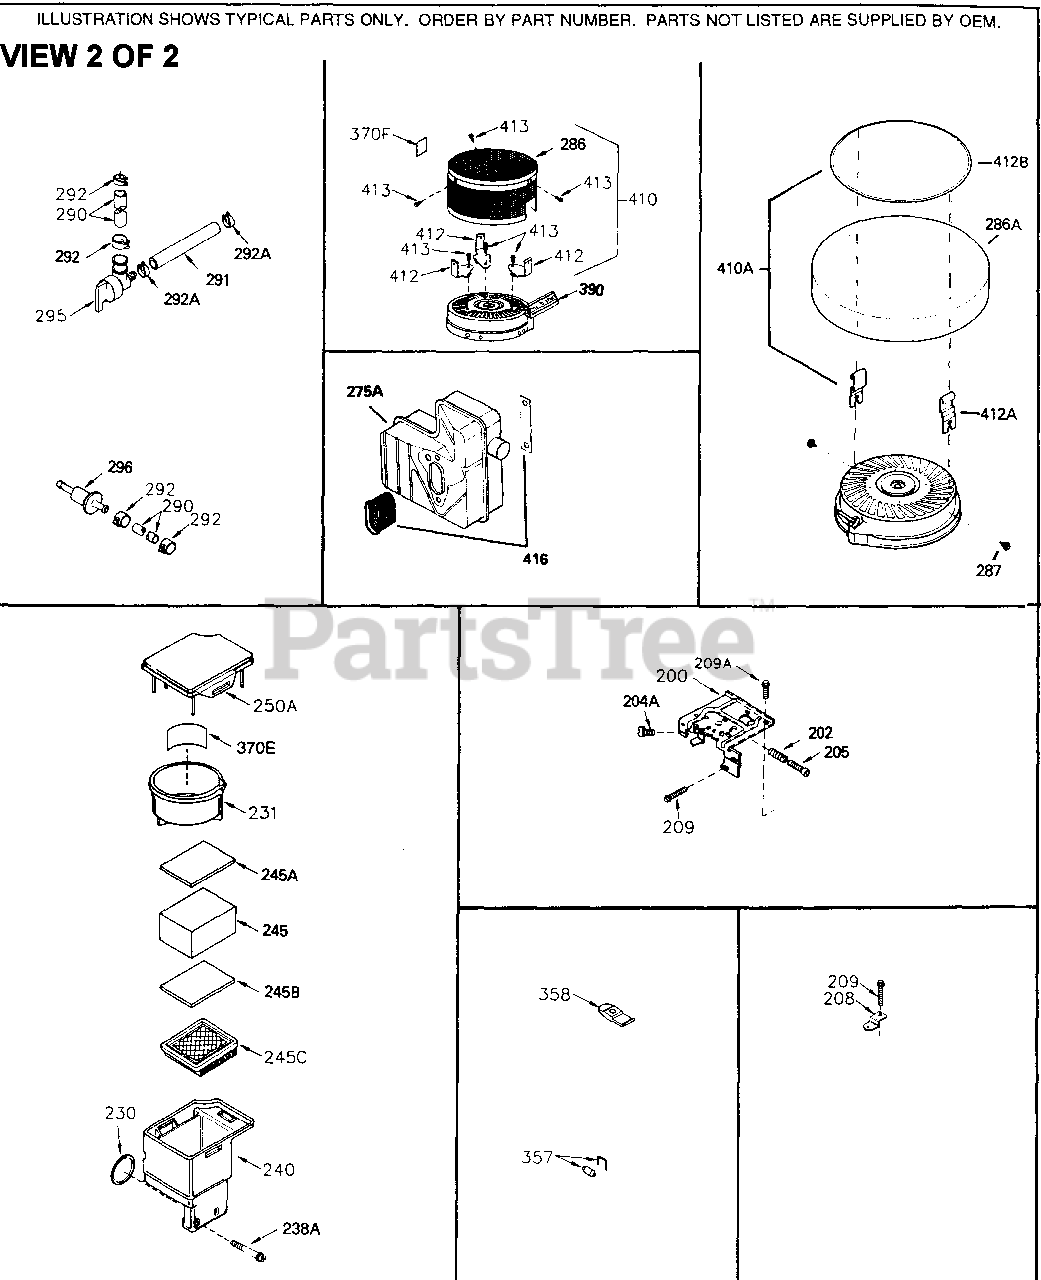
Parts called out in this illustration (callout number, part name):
200	Control Bracket (Incl. 202 thru 205)
202	Compression Spring
205	Screw, Torx T-10, 10-32 x 1-1/8"
209	Screw, 10-24 x 3/8"
209A	Screw, 10-24 x 1/2"
245	Air Filter
245A	Air Filter
286A	Starter Air Cleaner
287	Screw, 8-32 x 21/64"
290	Fuel Line (8.62")
291	Fuel Line (8.62")
292	Fuel Line Clamp
295	Fuel Shut-Off Valve (Incl. 292) also available in Packaged Part #740073
370E	Decal - XL/C industrial/Commercial Wi th Air Filter Service Info
370K	Starter Decal
390	Rewind Starter NOTE: This engine cou ld have been built with 590738 starte r.
410A	Starter Muff Kit Incl. 286A, 412A &41 2B
412A	Starter Air Cleaner Mounting Bracket
412B	Starter Air Cleaner Mounting Ring
